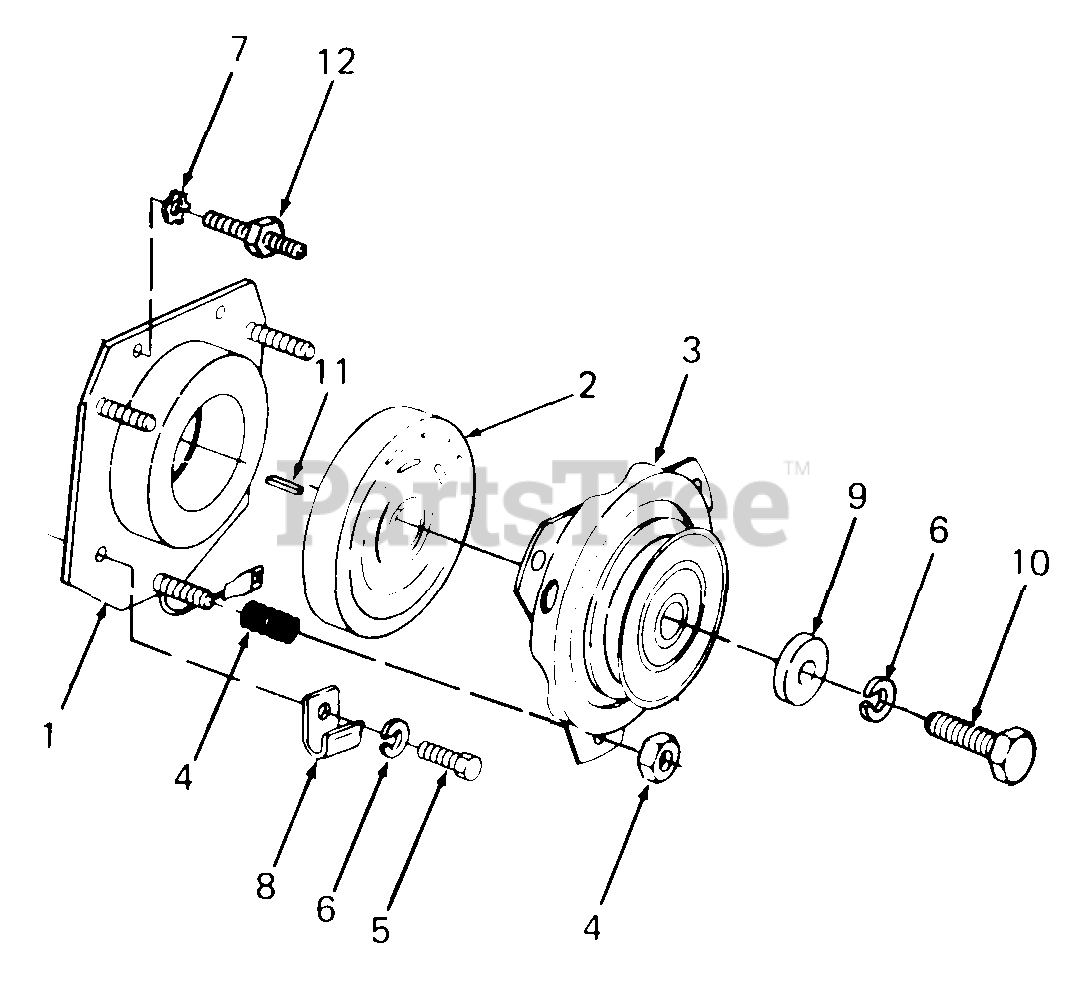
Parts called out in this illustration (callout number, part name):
4	Spring & Nut Kit
5	Screw, Hex Cap, 7/16-14 X .75 Lg GR5
6	Washer, Lock, 7/16
7	Washer, Ext. Lock, .45 X .75 X .035 Thk
8	Clamp, Cable
9	Washer, Flat, .47 X 1.5 X .225 Thk
10	Screw, Hex Cap, 7/16-20 X 1.50 Lg GR5
11	Key, Square, 1/4 X .75 Lg
12	Stud, 7/16-14 Trd
